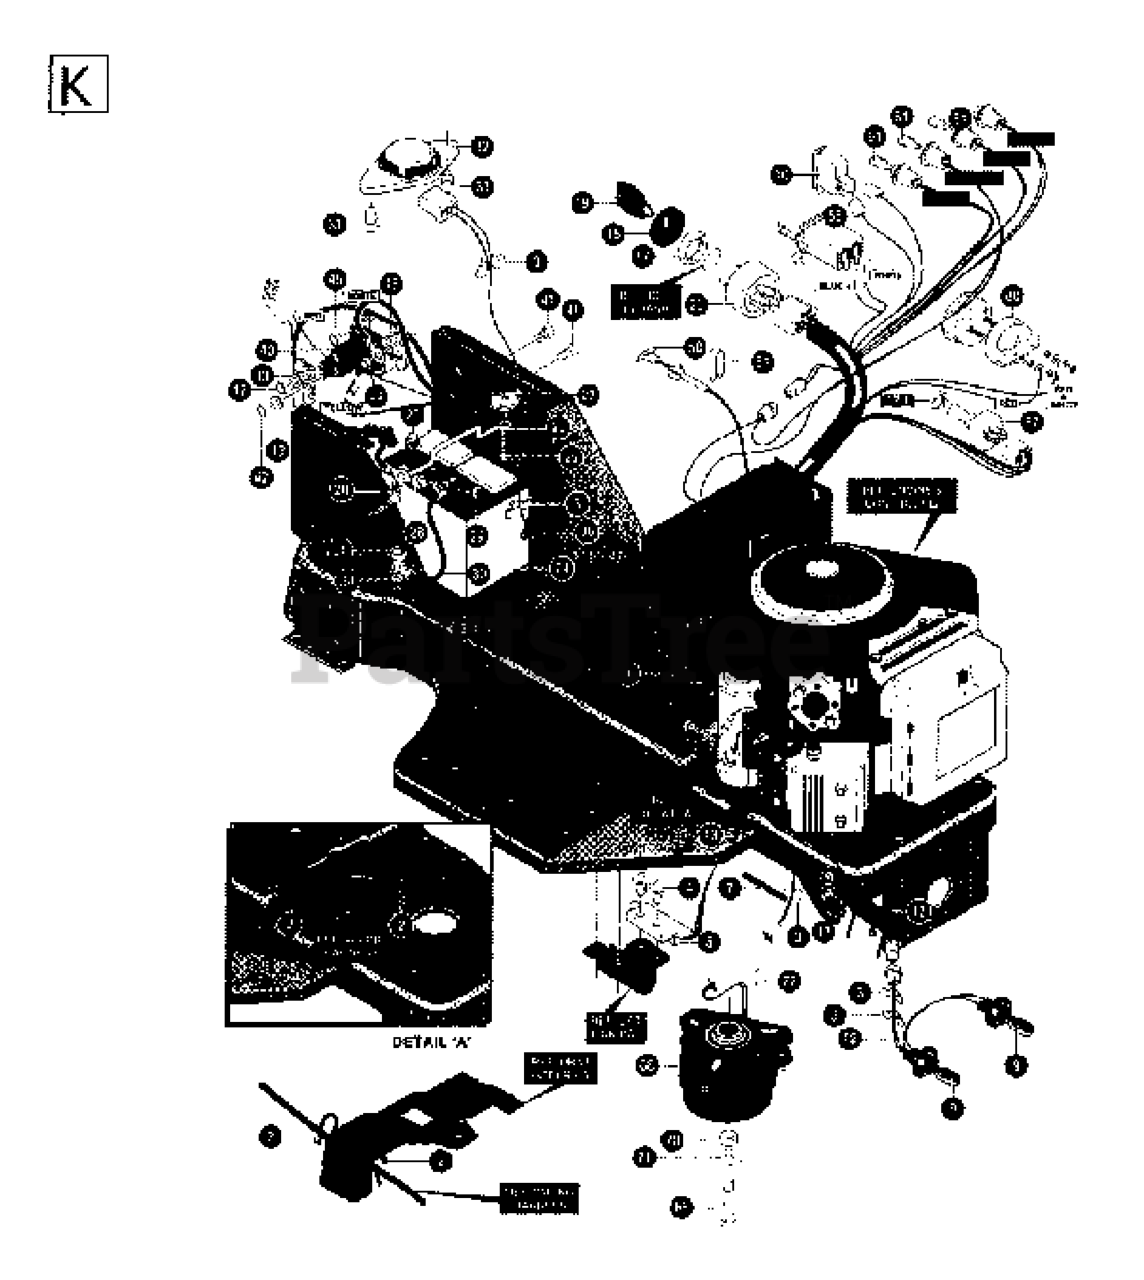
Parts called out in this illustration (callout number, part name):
2	TIE,CABLE
4	SCREW12X1/2ä
10	SWITCH, LIGHT
13	TIE,CABLE
18	DUST PROTECTION
24	BATTERY - DRY
28	BOLT.HEX.1/4.X.3/4.DICHROMATE
29	NUT
31	NUT 5/16X18
36	TIE,CABLE
42	NUT
43	LOCK WASHER
44	NUT
45	NUT
46	TIE,CABLE
50	CHOKE CONTROL
71	LOCK WASHER
